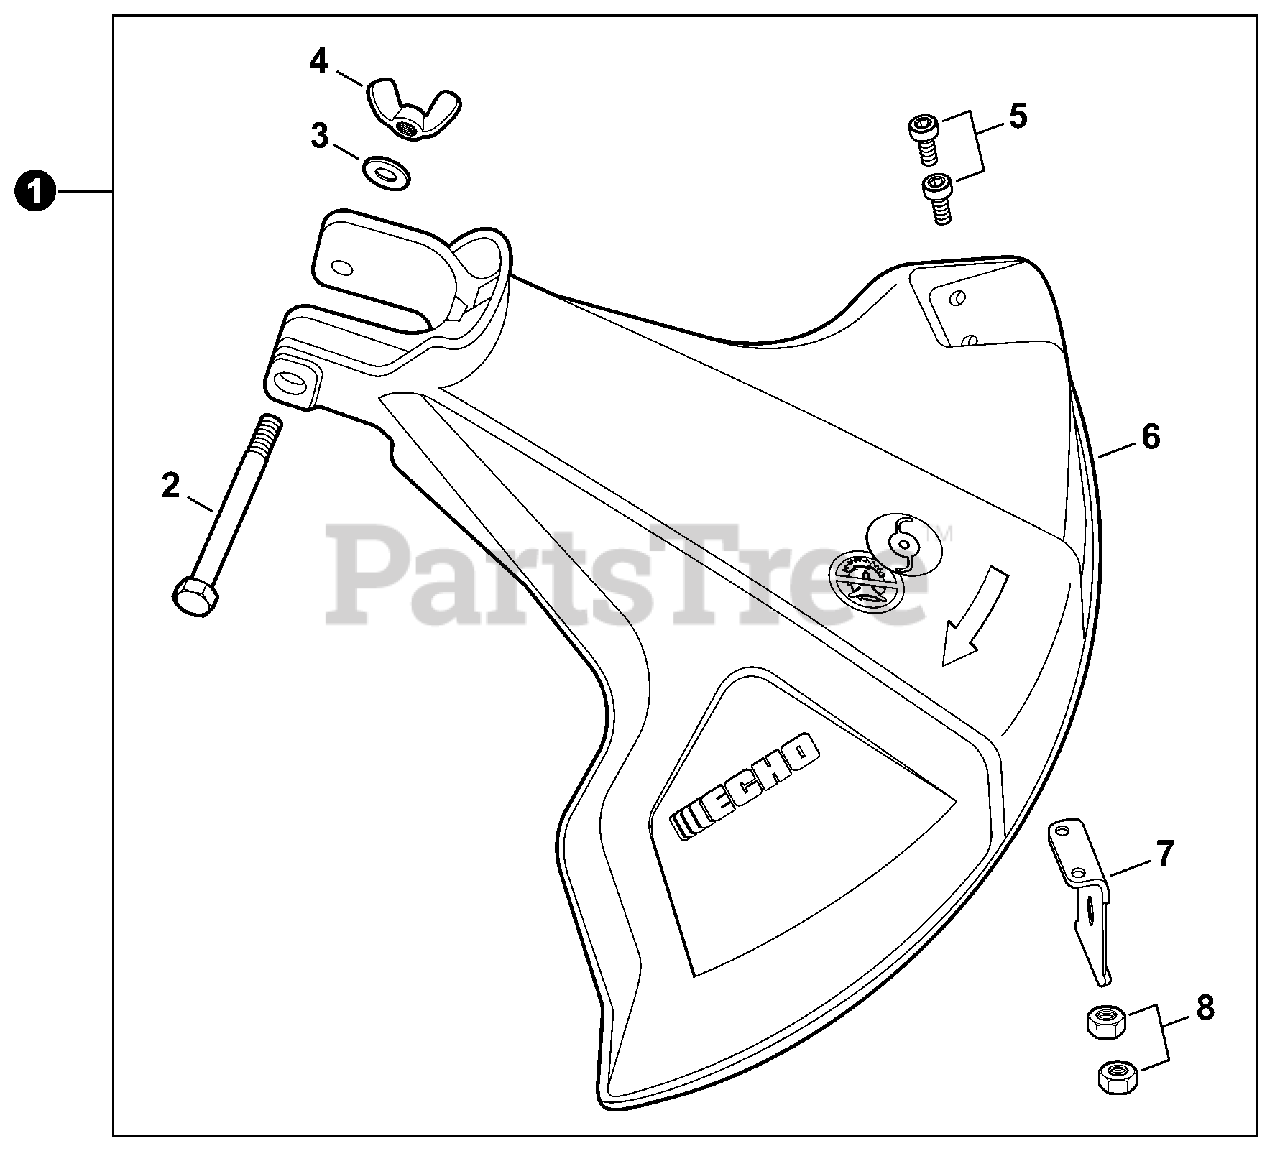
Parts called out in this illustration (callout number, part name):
1	DEBRIS SHIELD ASSY
2	BOLT 1/4"-20×2"
3	WASHER, 1/4"
4	NUT, WING 1/4"-20
5	BOLT, TORX 5×12
6	SHIELD, DEBRIS
7	CUTTER, LINE
8	NUT - 5
